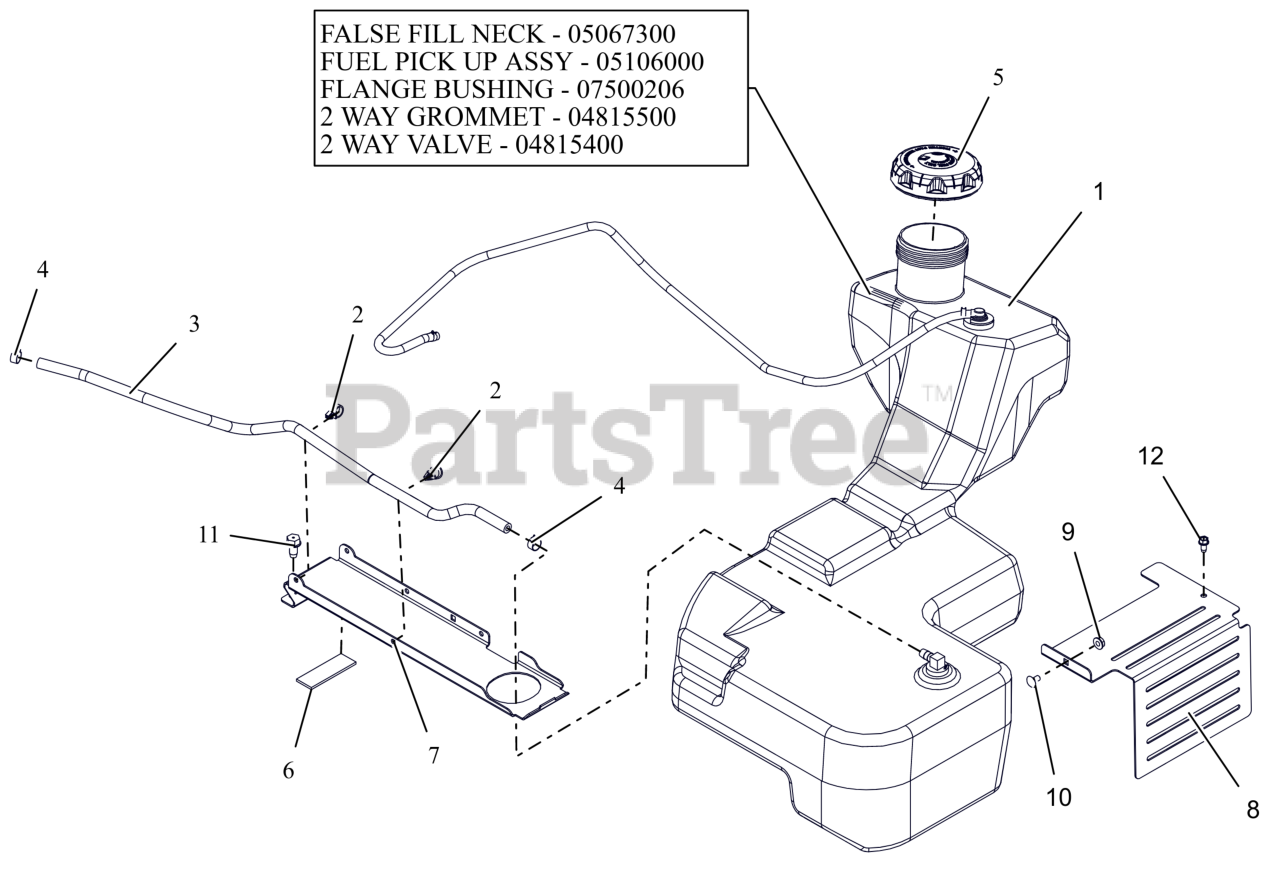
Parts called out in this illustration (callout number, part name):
1	ASM, FUEL TANK-HD
1	INSERT, FUEL NECK FALSE FILL
1	ASM, HD FUEL PICK-UP
1	BSHG-FLG .375X1.062X.625 NITR
1	GROMMET, 2-WAY
1	VALVE, 2-WAY
2	ROUTING CLIP (1/2" ID)
3	HOSE, .25 LOW-PERM BULK GAS
4	CLAMP, FUEL LINE
5	CAP, FUEL VENTIN AUTOLOCK
6	PAD,RBR 1.0"X3.0" W/ADHESIVE
7	BRKT, FUEL TANK HOLD DOWN
8	GUARD, TRANSAXLE FAN LH (BLACK)
9	NUT-LK-CTR-FLG .25-20 ZC120
10	BLT, RHSSN.25-20X.500 G5 ZCC
11	SCR,TAP .375-16X.75 HWH TR ZCC
12	SCR-TAP .25-20X.50 HWH ZCC
